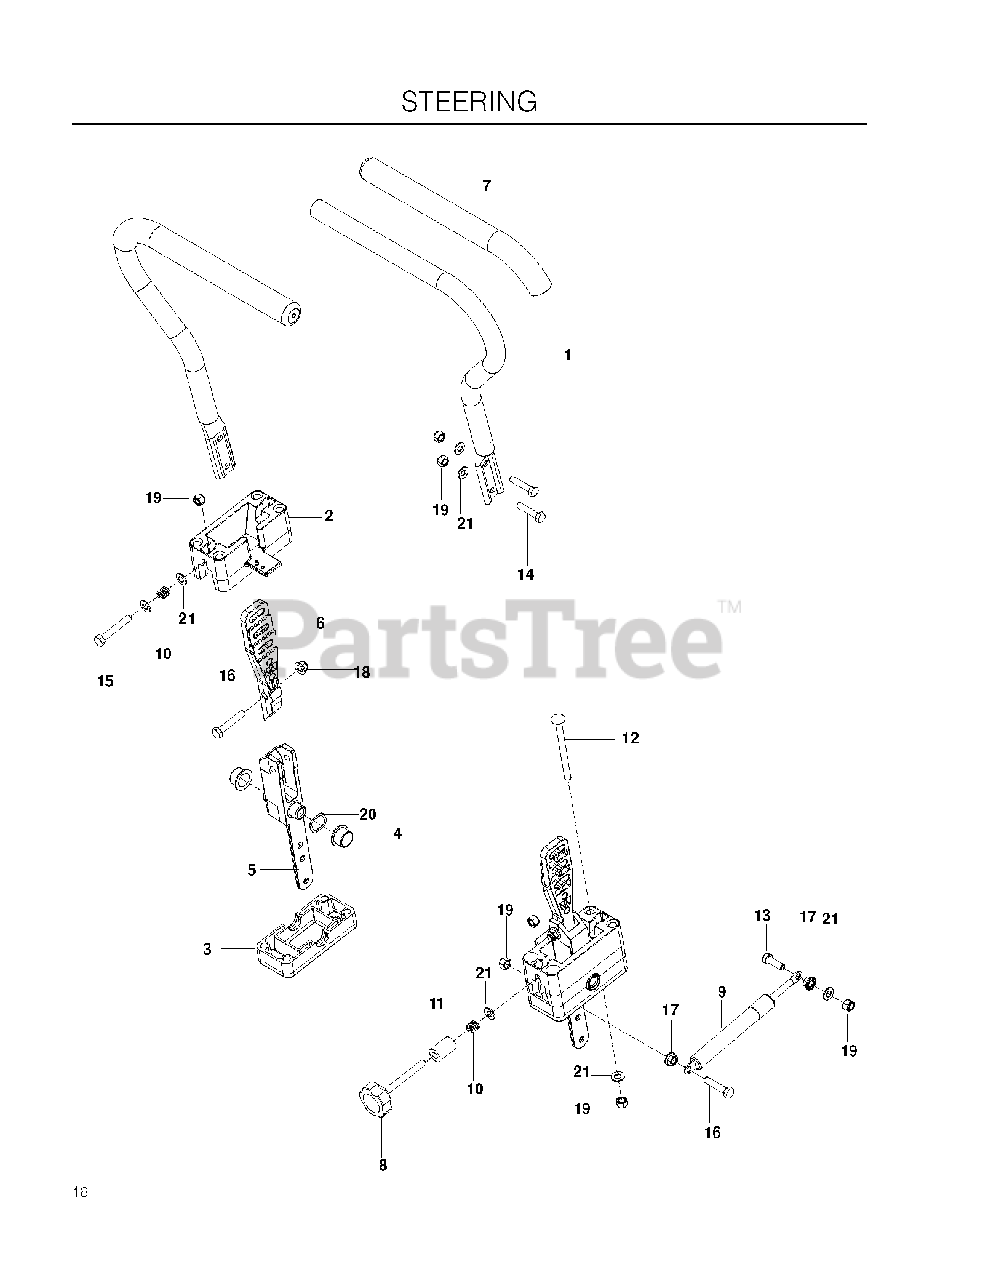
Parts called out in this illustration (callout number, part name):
1	ASSEMBLY, DRIVE LEVER
2	BLOCK, UPPER
3	BLOCK, LOWER
4	BEARING, FLANGE
5	PIVOT, SECTION, DRIVE, CONTROL
6	MOUNT, DR CNTRL HANDLE
7	GRIP, FOAM (GROUND) 15
12	RHSNB 5/16-18 X 4 GR 5 ZD
13	HCS 5/16C X 1
14	CAPSCREW 5/16 X 1/1/2 HEX HEAD
15	HCS 5/16-18 X 2 TPBLT GR 5 ZD
16	HCS 5/16C X 1 3/4
17	NUT 5/16C WHIZ
18	5/16-18 NYLOC FLANGE NUT
19	NUT 5/16 NYLOC
20	WASHER, .825 X 1.087, WAVE
21	FLAT WASHER 5/16 SAE
